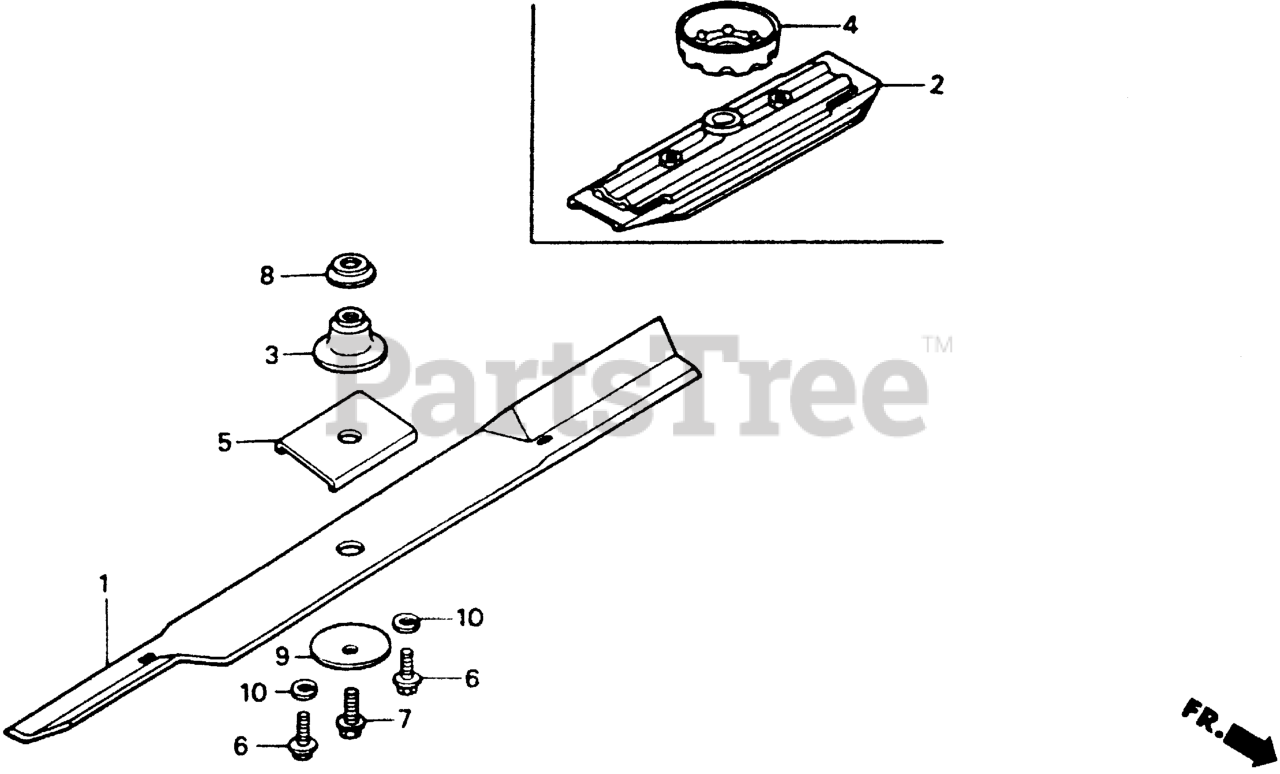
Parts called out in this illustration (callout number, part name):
1	BLADE, ROTARY
3	HOLDER, BLADE
5	HOLDER, BLADE (B)
6	BOLT, FLANGE (12X25)
7	BOLT, BLADE HOLDER (10X28)
8	WASHER, BLADE HOLDER
9	WASHER, BLADE
10	WASHER, SPRING (12MM)
